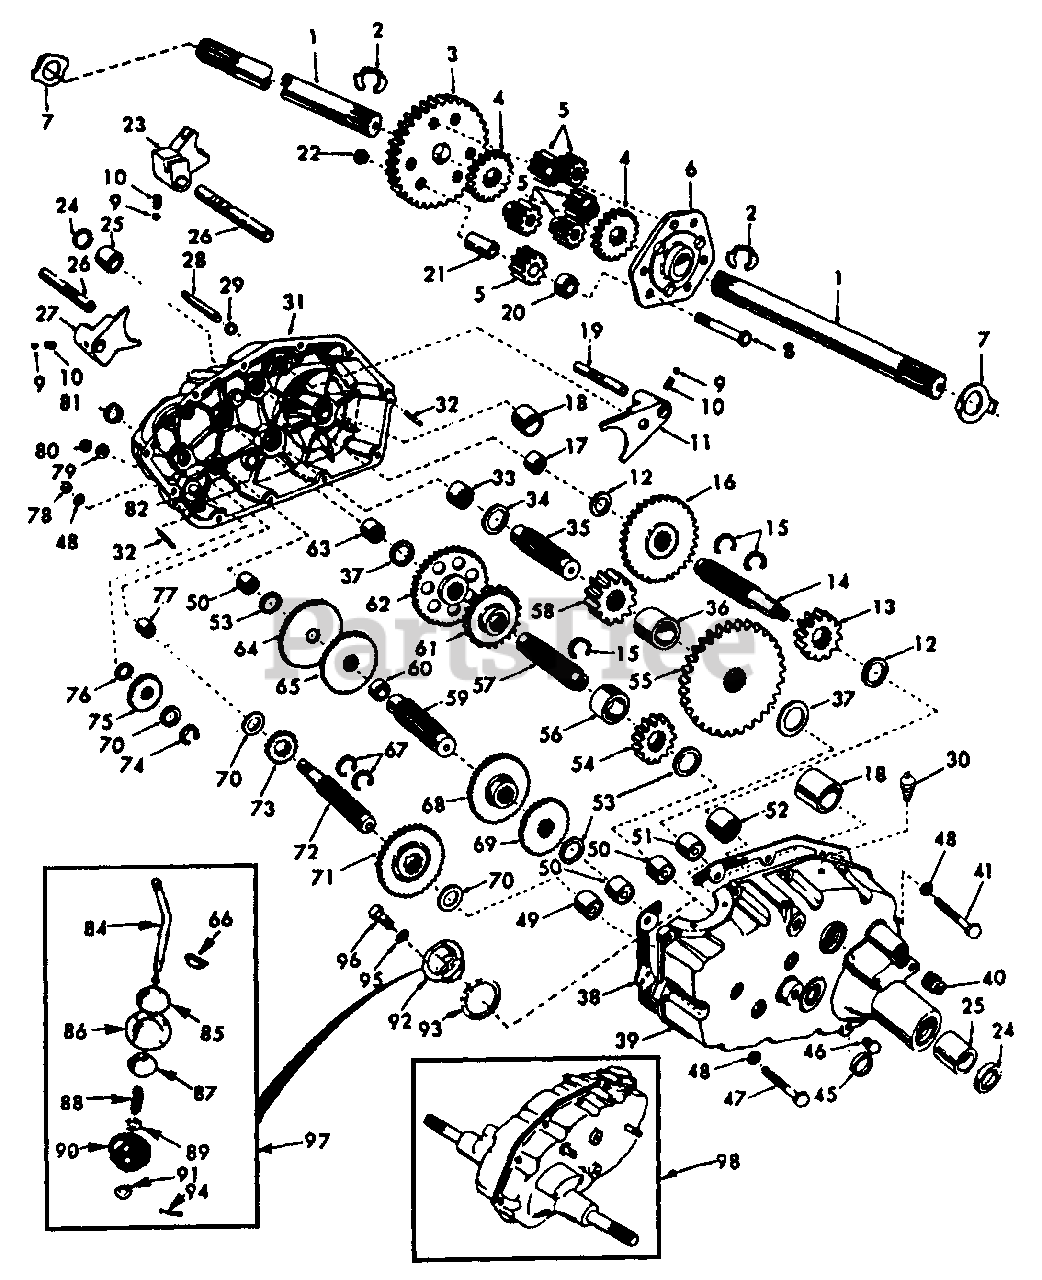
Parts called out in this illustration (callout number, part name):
1	Axle Shaft
2	Retaining Ring
3	Final Drive Gear
4	Differential Gear
5	Differential Pinion
6	Differential Carrier
7	Axle Thrust Washer
8	Bolt, Hex Head 3/8-24 x 3-1/4 (1" Thread Length)
9	Steel Ball
10	Spring Shift Fork Detent
11	Shift Fork, High-Low Range
12	Thrust Bearing Race
13	4th Reduction Pinion
14	3rd Reduction Gear Shaft
15	Snap Ring, Crescent Type
16	High -Low Range Gears
17	Needle Bearing
18	Sintered Iron Bearing
19	Shift Fork Shaft, Hi -Low Range
20	Differential Pinion Spacer
21	Differential Pinion Bushing
22	Gripco Centerlock Nut 3/8-24
23	Shift Fork, L.H.
24	Oil Seal
25	Sintered Iron Bearing
26	Shift Fork Shaft
27	Shift Fork, R.H.
28	Shift Shaft, High-Low Range
30	Pressure Relief Valve
31	Gearcase, Reverse Idler Shaft and Bearings, R.H.
33	Needle Bearing
34	Thrust Bearing Race
35	4th Reduction Gear Shaft
36	4th Reduction Gear Spacer
37	Thrust Bearing Race
38	Gearcase Gasket
39	Gearcase and Bearings, L.H.
40	Pipe plug 1/2-14 N.P.T.
41	Bolt, Hex 5/16-18 UNC x 1-5/8
46	Pipe Plug 1/4-18 N.P.T.
47	Bolt, Hex 5/16-18 x 1-1/2 Grade 5
48	Washer, Lock, Extra Heavy 5/16
49	Needle Bearing
50	Needle Bearing
51	Needle Bearing
52	Needle Bearing
53	Thrust Bearing Race
54	3rd Reduction Pinion, Low
55	4th Reduction Gear
56	3rd Reduction Pinion Spacer
57	2nd Reduction Gear Shaft
58	Final Drive Pinion
59	1st Reduction Gear Shaft
60	1st Reduction Shaft Spacer
61	3rd Reduction Pinion High
62	2nd Reduction Gear
63	Needle Bearing
64	Low Speed Gear and 2nd Reduction Pinion Cluster
65	Reverse Gear
66	Key, Hi-Pro 1/8 x 17/32
67	Snap Ring, Crescent Type
68	Intermediate Speed Gear
69	High Speed Gear
70	Thrust Bearing Race
71	Intermediate and High Speed Cluster Pinions
72	Input Shaft
73	Low Speed Pinion
75	Reverse Idler Gear
76	Reverse Idler Thrust Washer
77	Needle Bearing
78	Nut, Hex 5/16-18
79	Sealing Washer
80	Nut, Hex, Jam 7/16-20
81	Oil Seal
82	Reverse Idler Shaft
84	Gearshift Lever, Bent
85	Gearshift Cap
86	Gearshift Ball Cover and Pin
87	Shift Lever Guide Ball, Keyed
89	Washer 15/32 x 15/16 x 16 Gauge
90	Shift Mechanism Seal
91	Washer 9/16 x 15/16 x 12 Gauge
92	Gearshift Gate and Reinforcement
93	Shift Ball Cover Gasket
94	Cotter Pin 1/8 x 3/4
95	Washer, Lock 5/16
96	Bolt, Hex Head 5/16-18 UNC x 7/8
97	Gear Shift Lever Assembly
98	Transaxle Assembly
